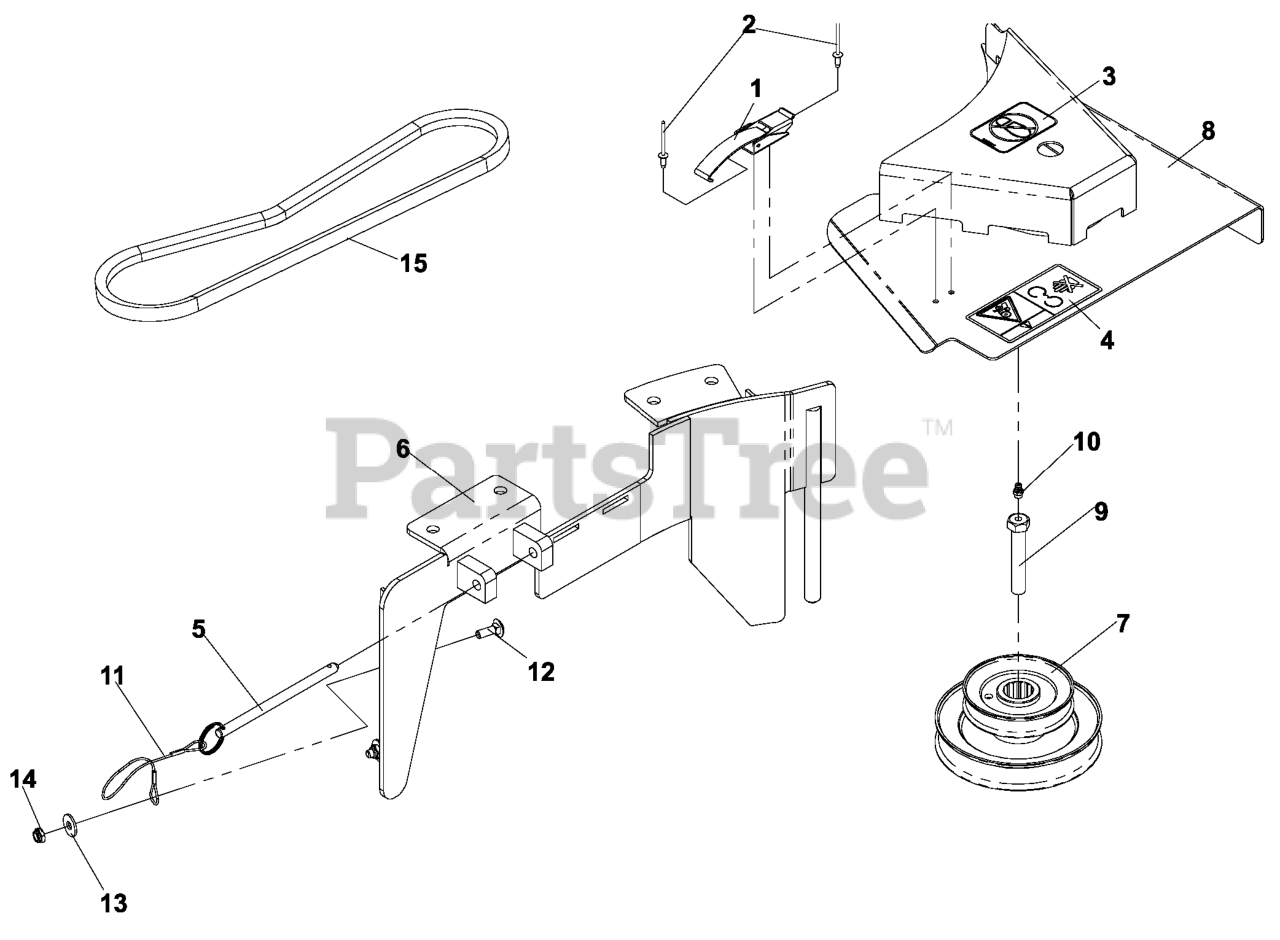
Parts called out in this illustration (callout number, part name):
1	DRAW LATCH
2	RIVET, BLIND, 5/32 DIA
3	DECAL, NO STEP
4	DECAL, BELT DRIVE
6	BLOWER DECK PLATE WLDMT, 52
7	52 LNG DOUBLE HEX STACK PULLEY
8	BELT SHIELD ASSY 52"
9	DRILLED BOLT 7/16-20 X 2 1/2"
10	ZERK
12	RHSNB 1/4C X 3/4
13	WASHER 1/4 FLAT
14	JAM NUT 1/4C (2 2 PW01)
